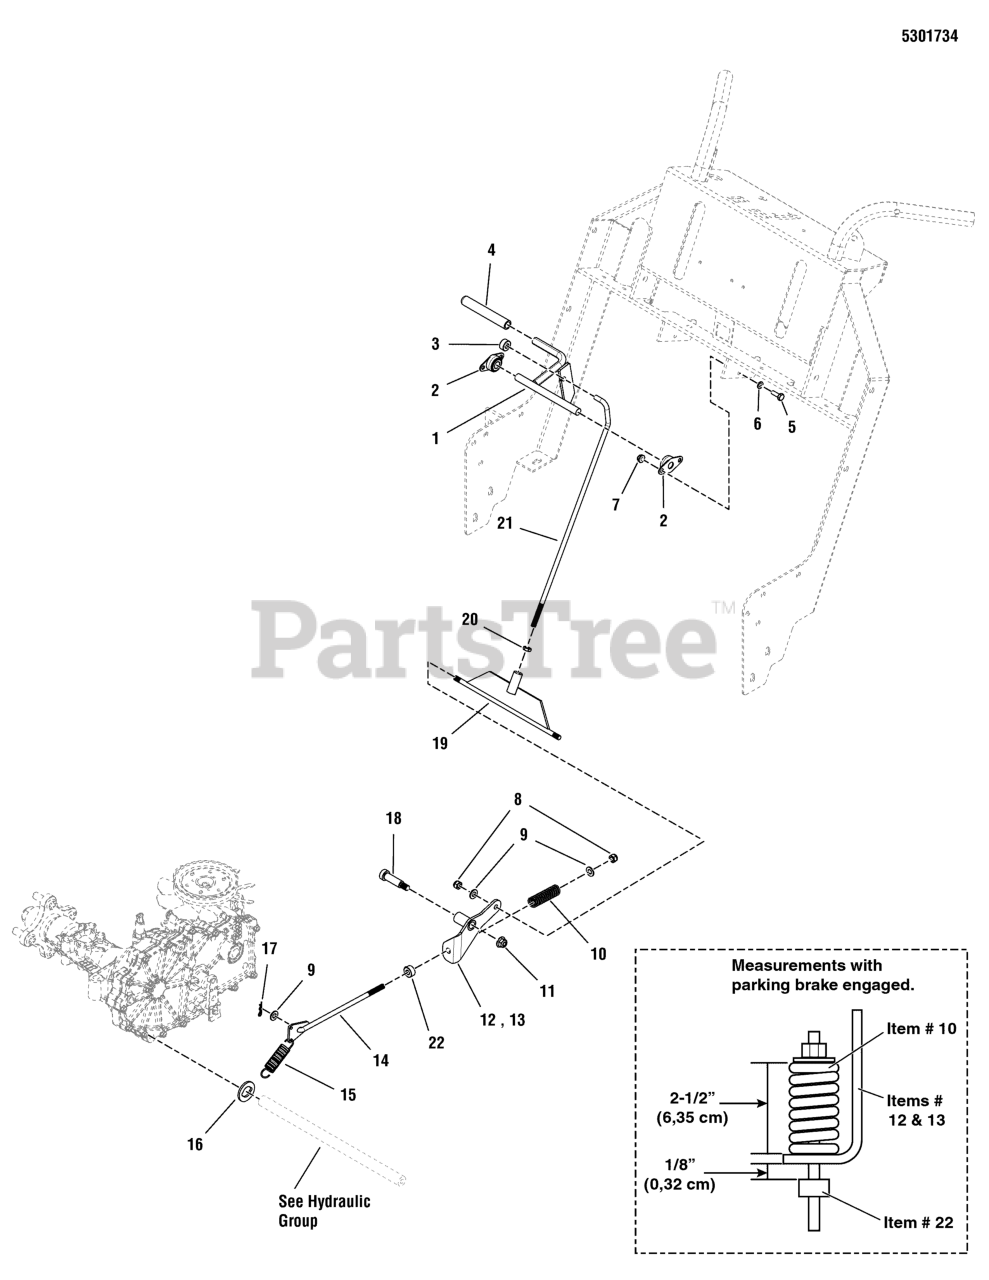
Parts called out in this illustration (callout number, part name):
1	WELD, BRAKE SHAFT, SW30 - RED
2	BEARING, 1/2 FLANGED, PLASTIC BALL
3	COLLAR, 5/16 SET
4	GRIP, FOAM
5	BOLT, 1/4-20 X 3/4 GD5 YZ
6	WASHER, 1/4 SAE
7	NUT, 1/4-20 HEX NYLOCK FLANGE
8	NUT, 5/16-24 HEX NYLON LOCK
9	WASHER, 5/16" SAE
10	SPRING-COMP, .496ID X 3.00LG X .112WR
11	NUT, 3/8-16 HEX NYLOCK FLANGE
12	WELD, BRAKE ARM, LH, SW30 - RED
13	WELD, BRAKE ARM, RH, SW30 - RED
14	ROD, LOWER BRAKE, SW30
15	SPRING-EXT, 3.281 x .751 x .075 WIRE
16	WASHER, KEYED, 1-1/2 OD
17	PIN, COTTER, 1/8 X 3/4
18	BOLT-3/8-16 x 1-1/2, 1/2 SHOULDER
19	BRAKE ROD, LOWER CONNECTION, SW30
20	NUT, 5/16-24 JAM
21	ROD, PULLER ROD
22	COLLAR, DOUBLE SPLIT, 5/16 CZ
